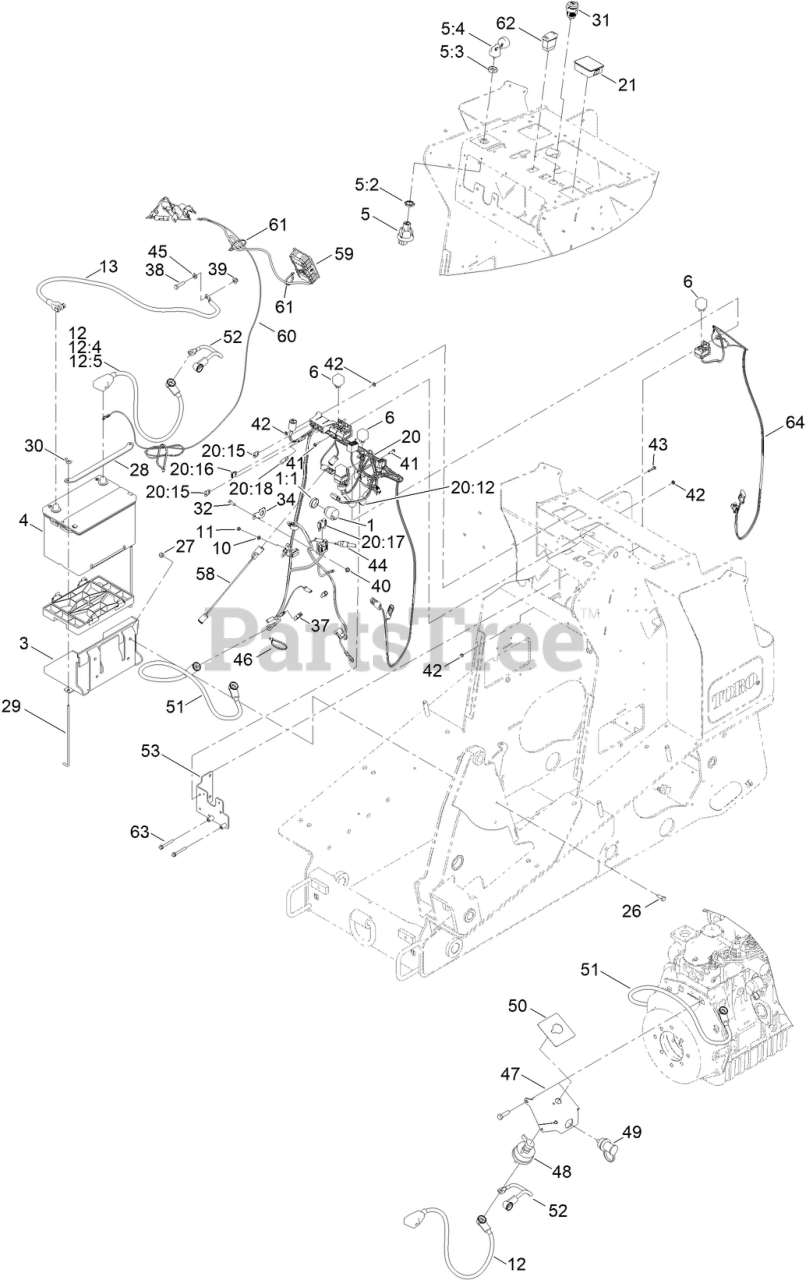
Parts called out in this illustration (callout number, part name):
1	AUDIO ALARM ASM
1:1	NUT-PLASTIC, KNURLED
3	TRAY-BATTERY
4	BATTERY
5	IGNITION SWITCH ASM
5:2	NUT-HEX
5:3	NUT-FACE
5:4	SET-KEY, IGNITION
10	WASHER-LOCK, SPRING
11	NUT-HEX
12	CABLE-BATTERY, POS ASM
12:4	BOLT-BATTERY CLAMP, 5/16-18 UNC
12:5	NUT-CLAMP, BATTERY
13	CABLE-NEGATIVE
20	HARNESS-WIRE, TX1000
20:15	FUSE-BLADE, 10 AMP
20:16	FUSE-BLADE, 15 AMP
20:17	FUSE-BLADE, 50 AMP
20:18	CAP-PLUG
21	MODULE-HOUR METER
26	SCREW-HH
27	NUT-LOCK, NI
28	STRAP-HOLD DOWN, BATTERY
29	ROD-HOLD DOWN, BATTERY
30	NUT-WING
31	RECEPTACLE-12V
32	SCREW-HH
34	CLIP-FUSE
37	HARNESS-LINK, FUSIBLE
38	SCREW-HH
39	NUT-HF, NI
40	NUT-HF
41	SCREW-HWH
42	NUT-KEPS
43	SCREW-HWHTF
44	SWITCH-TEMP
45	WASHER-PLAIN
46	TIE-CABLE
47	MOUNT-REMOTE TERMINAL
48	SWITCH-DISCONNECT, MASTER
49	STUD-JUMPER, POSITIVE
50	DECAL-BATTERY DISCONNECT
51	CABLE-BATTERY, POSITIVE
52	CABLE-BATTERY, POSITIVE
58	HARNESS-WIRE
59	M7L-LITE ZTR KIT ASM
60	HARNESS-WIRE, MACHINE ZTR
61	TIE-CABLE
62	SWITCH-INTERMITTENT
63	SCREW-HHF
64	HARNESS-WIRE, AUX HOLD
